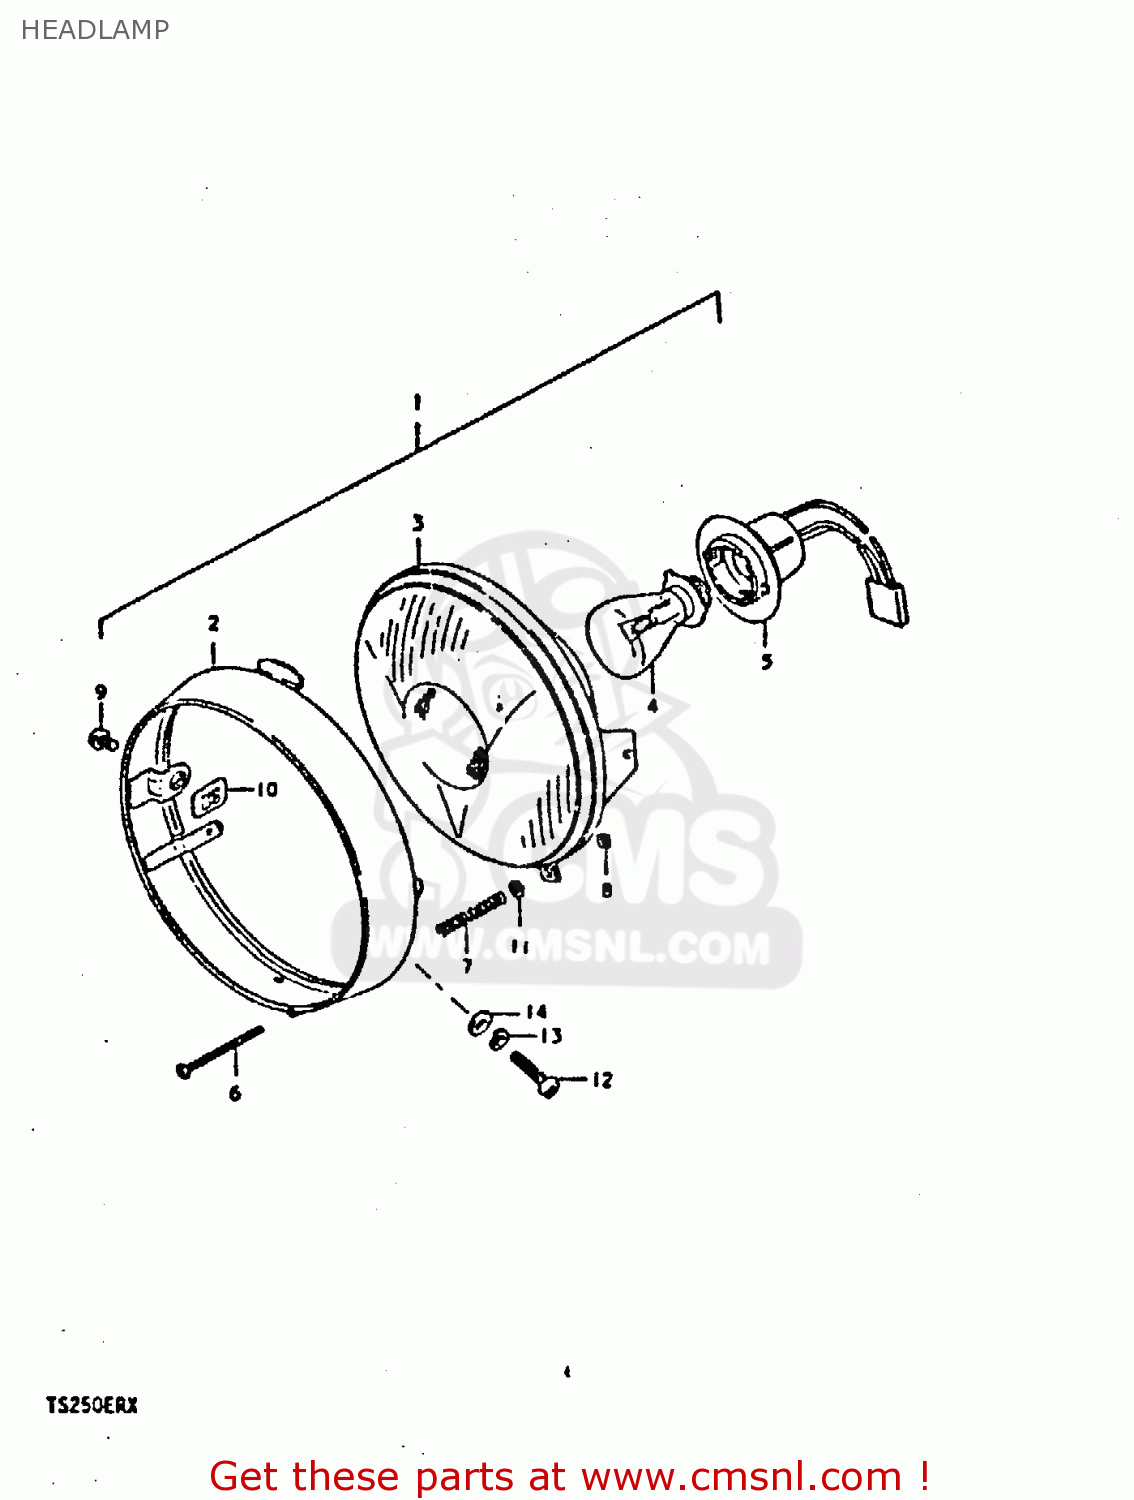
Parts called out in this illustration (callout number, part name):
1	HEADLAMP ASSY
2	RIM
3	LAMP UNIT
4	BULB(6V25/25W,STANLEY,A7007)
5	SOCKET,HEADLAMP
6	SCREW,HEADLAMP ADJUST
7	SPRING
8	NUT,HEADLAMP ADJUSTER
9	SCREW
10	NUT
11	WASHER
12	SCREW
13	LOCK WASHER
14	WASHER
